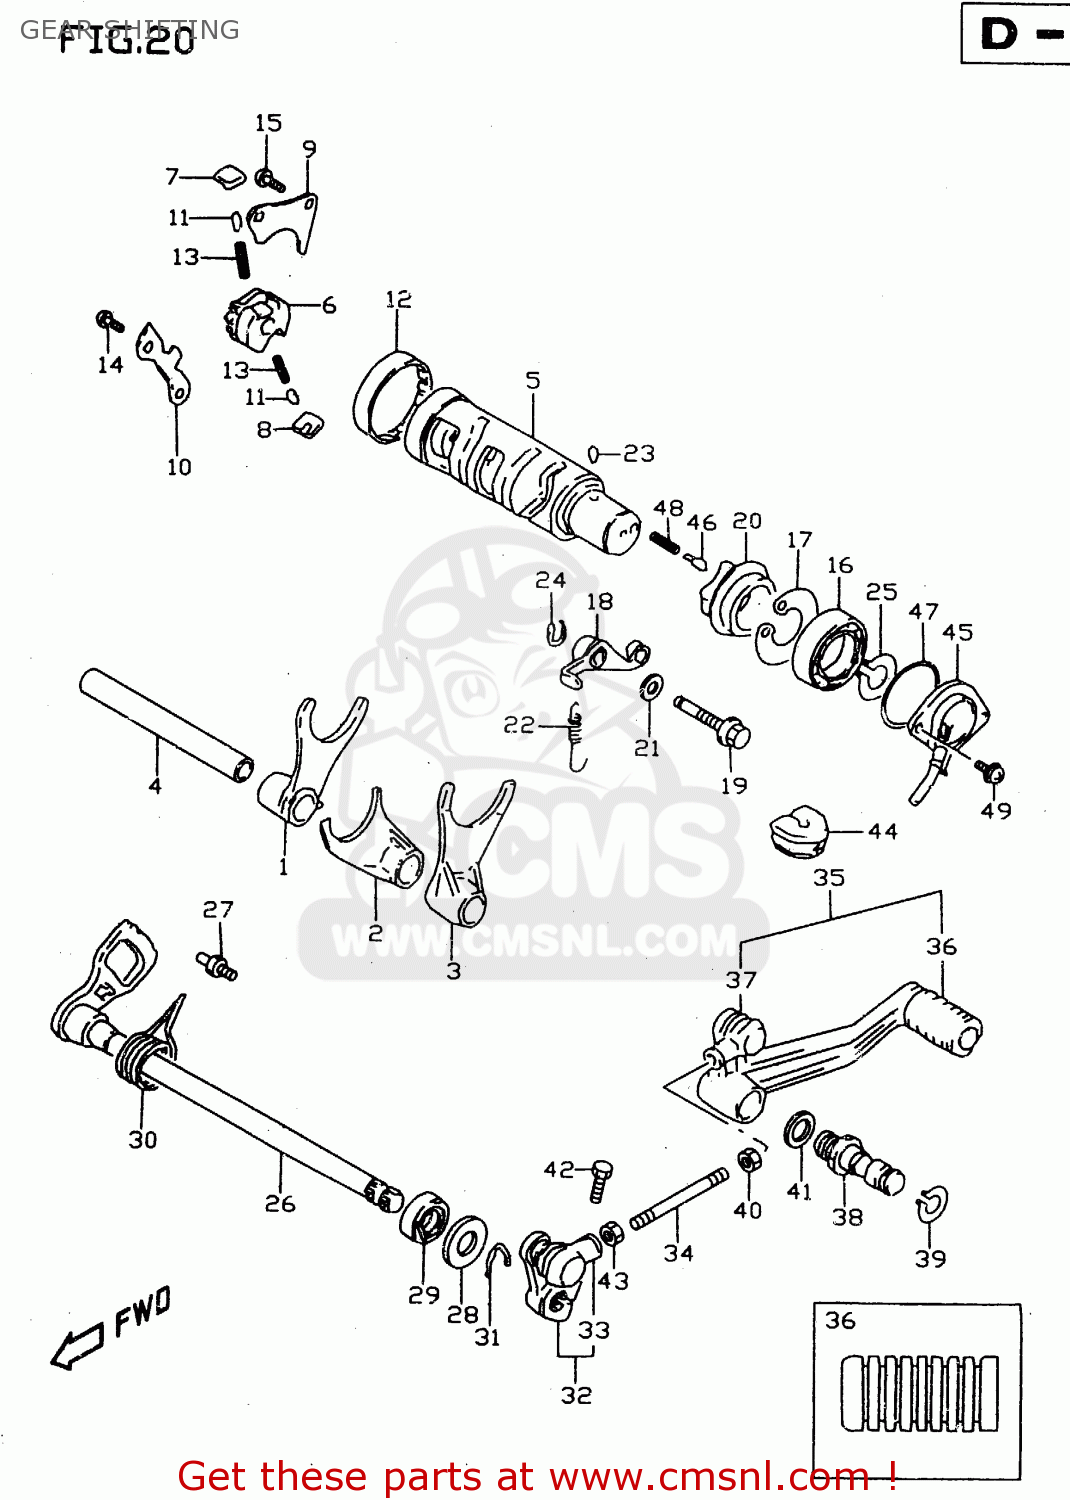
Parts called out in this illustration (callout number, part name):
1	FORK,GEAR SHIFT NO.1
2	FORK,GEAR SHIFT NO.2
3	FORK,GEAR SHIFT NO.3
4	SHAFT,GEAR SHIFT FORK(L:128)
5	CAM,GEAR SHIFT
6	GEAR,GEAR SHIFT CAM DRIVEN
7	PAWL,GEAR SHIFT NO.1
8	PAWL,GEAR SHIFT NO.2
9	LIFTER,GEAR SHIFT PAWL
10	GUIDE,GEAR SHIFT CAM
11	PIN(5X8)
12	BEARING(43X49X12)
13	SPRING
14	SCREW
15	SCREW
16	BEARING
17	CIRCLIP
18	STOPPER,GEAR SHIFT CAM
19	SHAFT,GEAR SHIFT CAM STOPPER
20	PLATE,STOPPER
21	GASKET(10X14X3.6) (NAS)
22	SPRING
23	PIN
24	CIRCLIP
25	CIRCLIP
26	SHAFT,GEAR SHIFT
27	STOPPER,GEAR SHIFT CAM
28	WASHER (12.5X26X1.6)
29	OIL SEAL
30	SPRING
31	CIRCLIP,12 MM
32	ARM,GEAR SHIFT LINK
33	COVER,DUST
34	ROD,GEAR SHIFT LINK
35	LEVER ASSY,GEAR SHIFT
36	RUBBER,GEAR SHIFT PEDAL
37	COVER,DUST
38	SHAFT,GEAR SHIFT LEVER
39	CIRCLIP,12 MM
40	NUT
41	WASHER(12.5X20X1)
42	BOLT
43	NUT
44	GROMMET,LEADWIRE
45	BASE ASSY,GEAR SHIFT TERMINAL
46	PIN(5X15.5)
47	O RING(D:2.4,ID:35.5)
48	SPRING
49	SCREW
